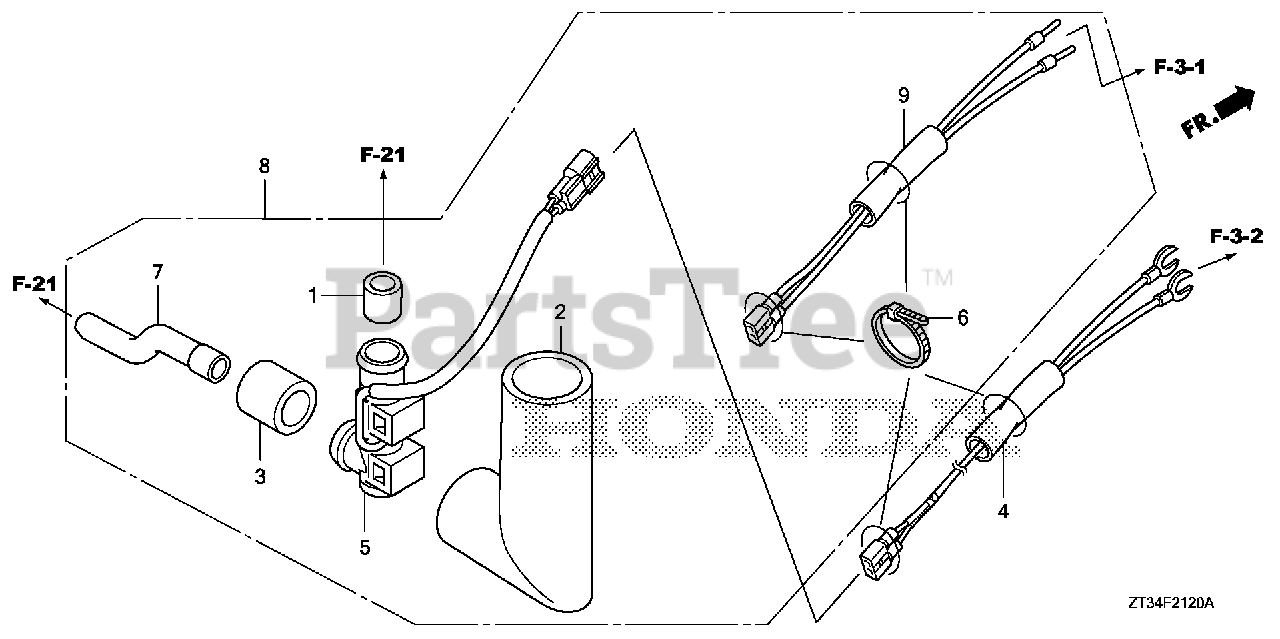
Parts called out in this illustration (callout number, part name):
1	TUBE B, BREATHER
2	INSULATOR L, BREATHER TUBE
3	INSULATOR, BREATHER TUBE
5	HEATER ASSY., BREATHER (L)
6	BAND A, HARNESS (NATURAL)
7	TUBE A, BREATHER
8	HEATER KIT, BREATHER
9	SUB-WIRE ASSY.
